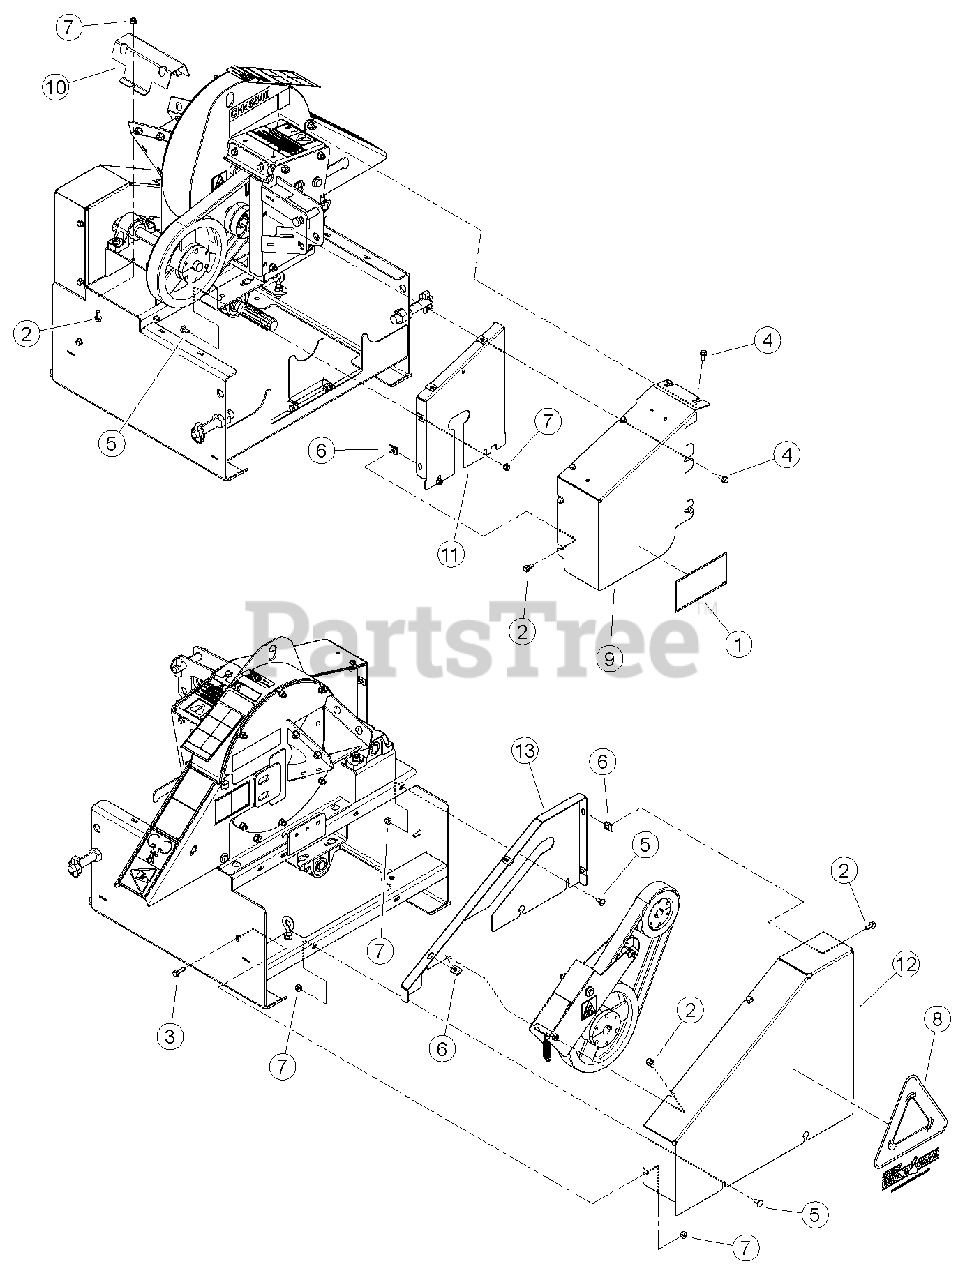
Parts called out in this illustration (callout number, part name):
1	DECAL, PTO DANGER ISO
2	BOLT, 5/16 X 3/4 FLANGE NC
3	BOLT, 5/16 X 1 FLANGE NC
4	BOLT, 5/16 X 5/8 FLANGE NC
5	BOLT, 5/16 X 3/4 GR5 NC ZP CRG
6	NUT, 5/16"-18 TINNERMAN U-TYPE
7	NUT, 5/16-18 NYLOCK FLANGE
8	DECAL, CHIP IT LARGE
9	SHIELD, FRONT BELT
10	SHIELD, JACKSHAFT
11	SHIELD, BACK BELT
12	SHIELD, FORWARD BELT
13	SHIELD, REAR BELT
